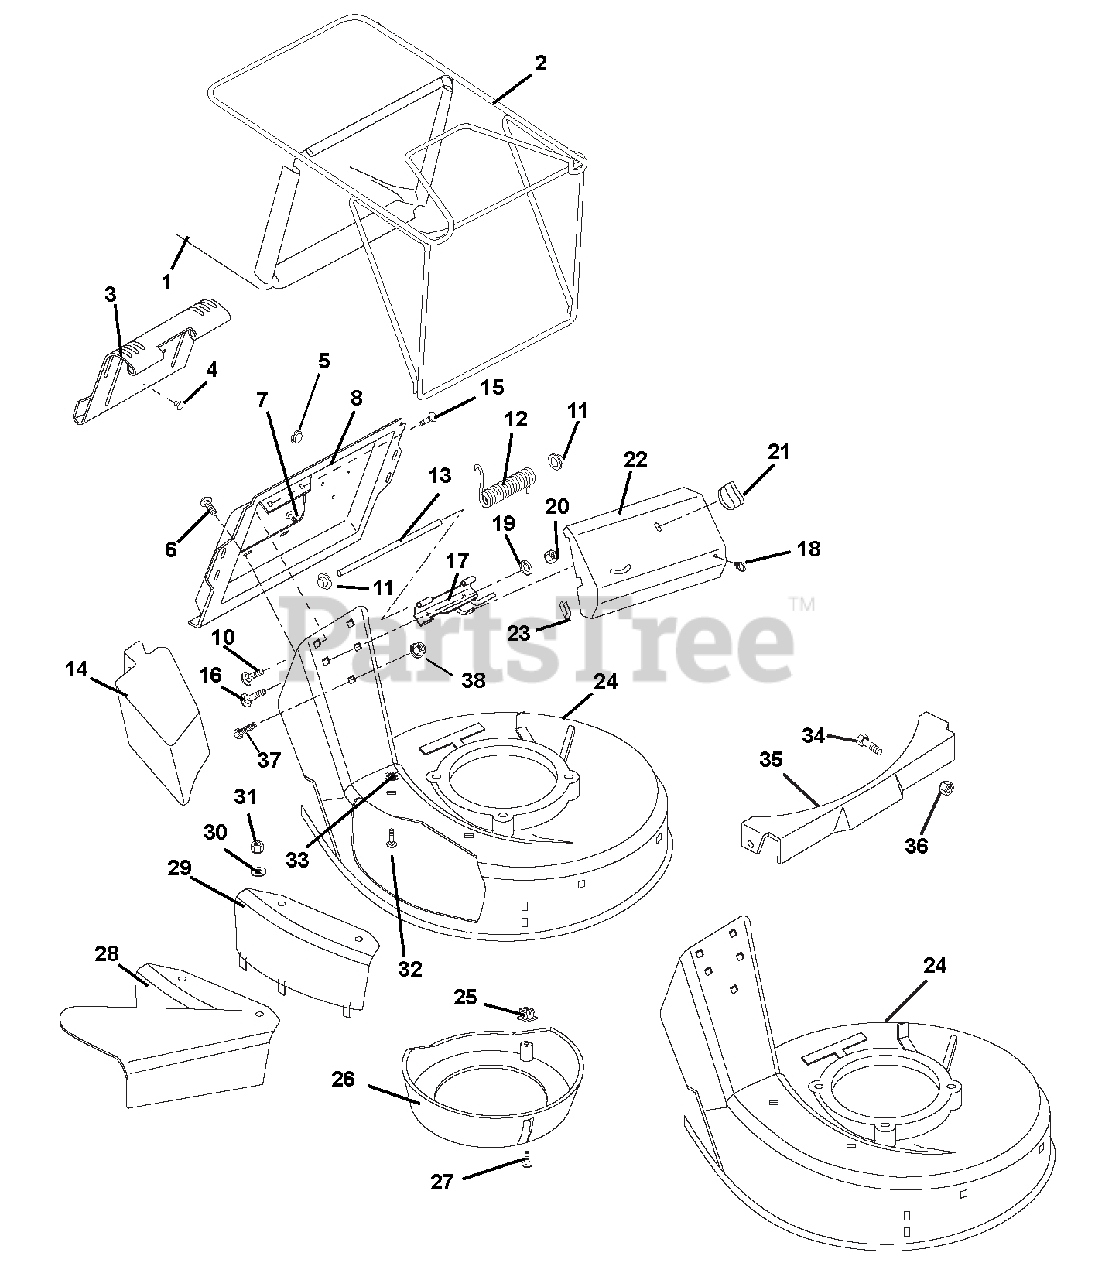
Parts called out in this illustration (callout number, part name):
1	BAG, CONSUMER BLACK 15 OZ/YD2
2	FRAME, BAGGER
3	CATCHER PLATE DOOR
4	BUTTON BUMPER
6	@SCR-TAP 12-24X.50 HWH TR YWZC
7	SCR-TAP 10-24X.375 TORX PHD YZ
8	CATCHER PLATE
9	PLATE, CATCHER
10	@BLT-RHDSSQNK .25-20X.38 G2YZ
11	PUSH NUT, .25
12	SG-TORS .120X.68X3.09
13	DOOR PIN
14	MULCH MASTER MULCHER ACCESSORY
15	@NUT-SPNLK-FLG .25-20 YWZC
16	@BLT-RDHDSQNK .25-20X.75 G5YZ
17	HINGE BASE WELDMENT
18	SNAP-IN CLIP
19	WSHR-LK .250X.077 HVY YWZC
20	@NUT-HEX .25-20 YWZC
21	WING - NUT
22	COVER, DRIVE
23	TRIM BUMPER
24	MOWER PAN HEAD W/SFTYDECALS SP
25	PLASTIC GROMMET
26	CENTER BAFFLE
27	SCR-TAP 10-16X.62 SLPH AB YWZC
28	SIDE DISCHARGE ASSEMBLY
29	COVER, SIDE DISCHARGE
30	@WSHR-FL-STL.406X.812X.065 YWZ
31	@NUT-LK-NYL .312-18 YWZC
32	BLT-RDHDSQSHK.31-18X.75 GR2 YW
33	NUT-PUSH .312
34	@BLT-RDHDSQNK .31-18X.50 G5YZ
35	PANEL-FRONT
36	@NUT-LK-TOP-FLG .31-18 YWZC
37	@BLT-HEX .38-16X.50 GR5 YWZC
38	@NUT-SPNLK-FLG .375-16 YWZC
